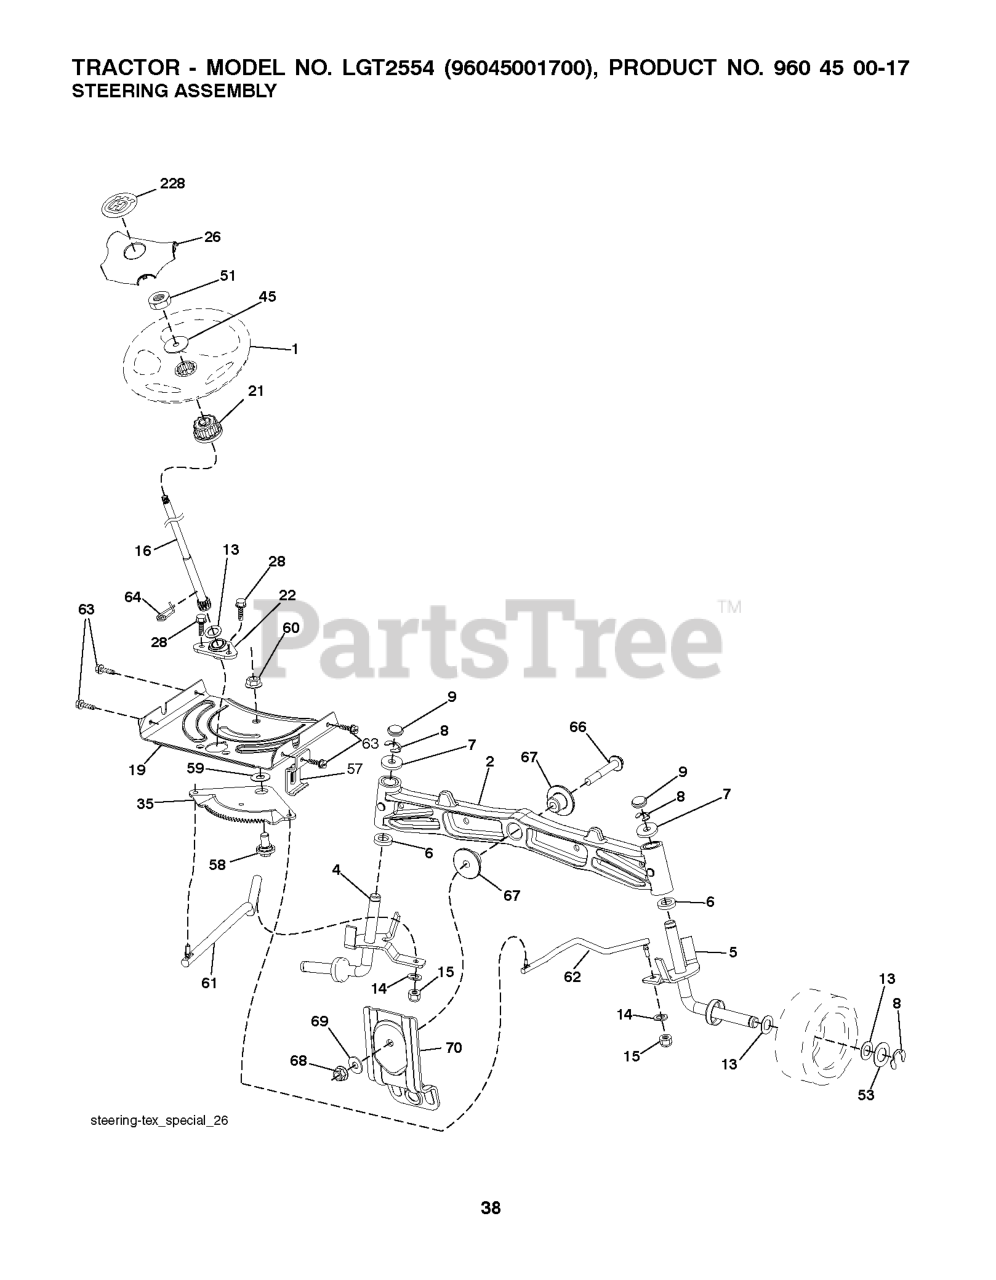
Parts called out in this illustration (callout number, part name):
1	WHEEL STEERING
2	AXLE.CAST.IRON
4	SPINDLE.WELDED.LH.16"TEX
5	SPINDLE.WELDED.RH.16"TEX
6	THRUST WASHER
9	CAP.SPINDLE.BLACK
14	WASHER, LOCK 3/8
15	NUT CROWNLOCK 3/8-24
16	SHAFT, STEERING
19	PLATE.STEER.DDL.NLT/NG
21	ADAPTER, WHEEL STNG..
22	BUSHING.ASM.STEERING.A
26	RP INSERT.CAP.WHL.STRG.HUSQ.
28	SCREW, 3/8-16X3/4
35	GEAR.SECTOR.PLATE.DDL.
45	WASHER 9/16"ID, 2 3/8"OD
51	NUT.HEX.1/2-20
53	WASHER.HARDENED
57	BRKT.UPSTOP.GT/LT.TEX
58	BOLT.SHOULDER.SECTOR.P
59	WASHER.THURST.SECTOR.S
60	NUT FLANGE LOCK 5/8-11
61	DRAGLINK.LH.BALLSTUD.D
62	DRAGLINK.RH.BALLSTUD.D
63	SCREW
64	RETAINER.CLIP.SPRING.S
66	BOLT HEX FGHD 7/16-14 X 3 SERR
67	BUSHING.PM.FRONT AXLE
68	NUT.LOCK.FLANGE.7/16
69	WASHER.1.5X.505X.118
70	BRKT.DECK.SUSPENSION.F
228	DECAL.WHEEL.STRG.LGN.H
